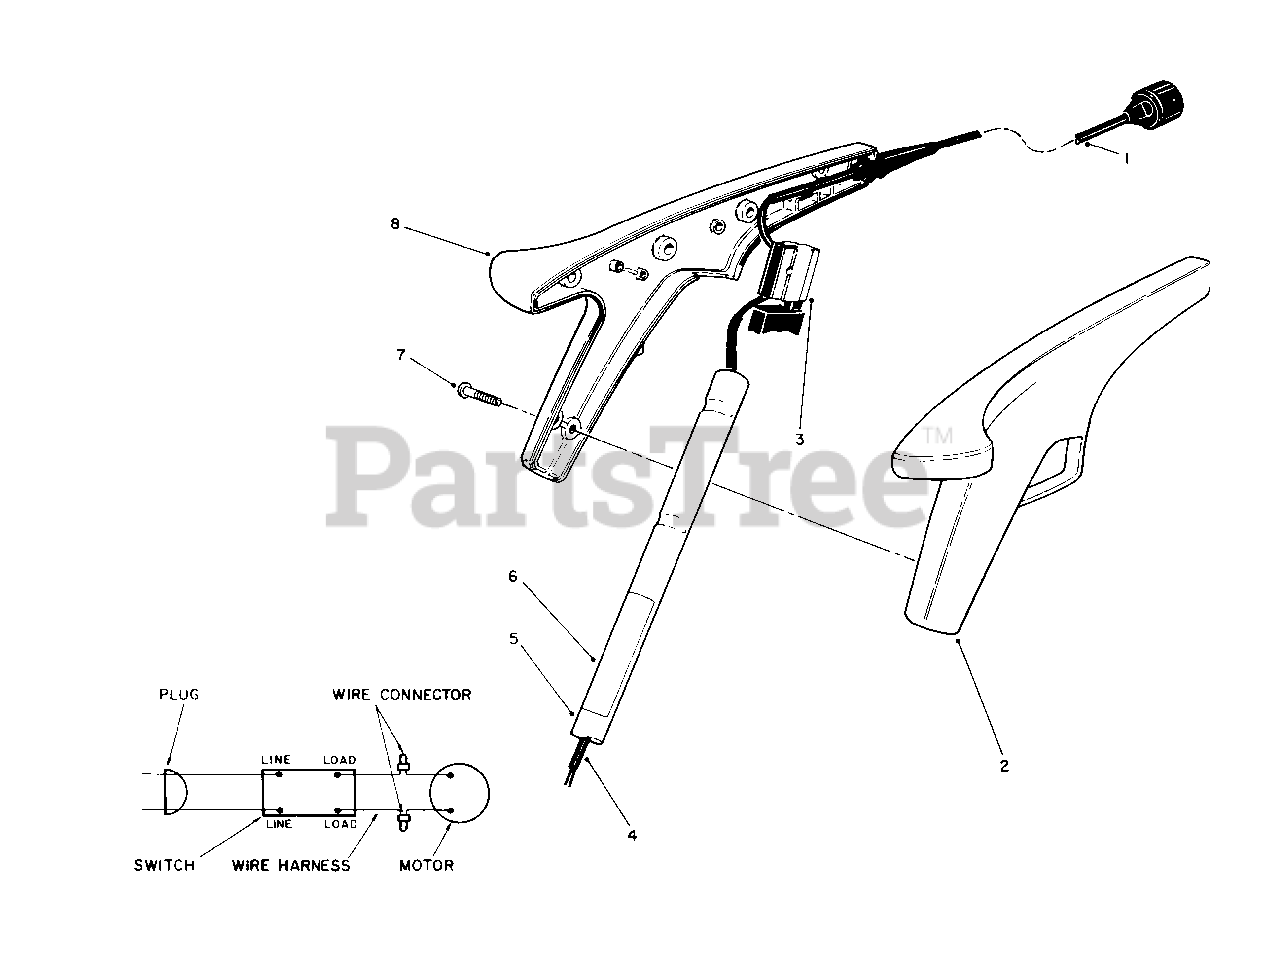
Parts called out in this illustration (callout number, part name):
1	Cord-Power
2	Grip-L.H.
4	Harness-Wiring
6	Decal-Serial
8	Grip-R.H.
